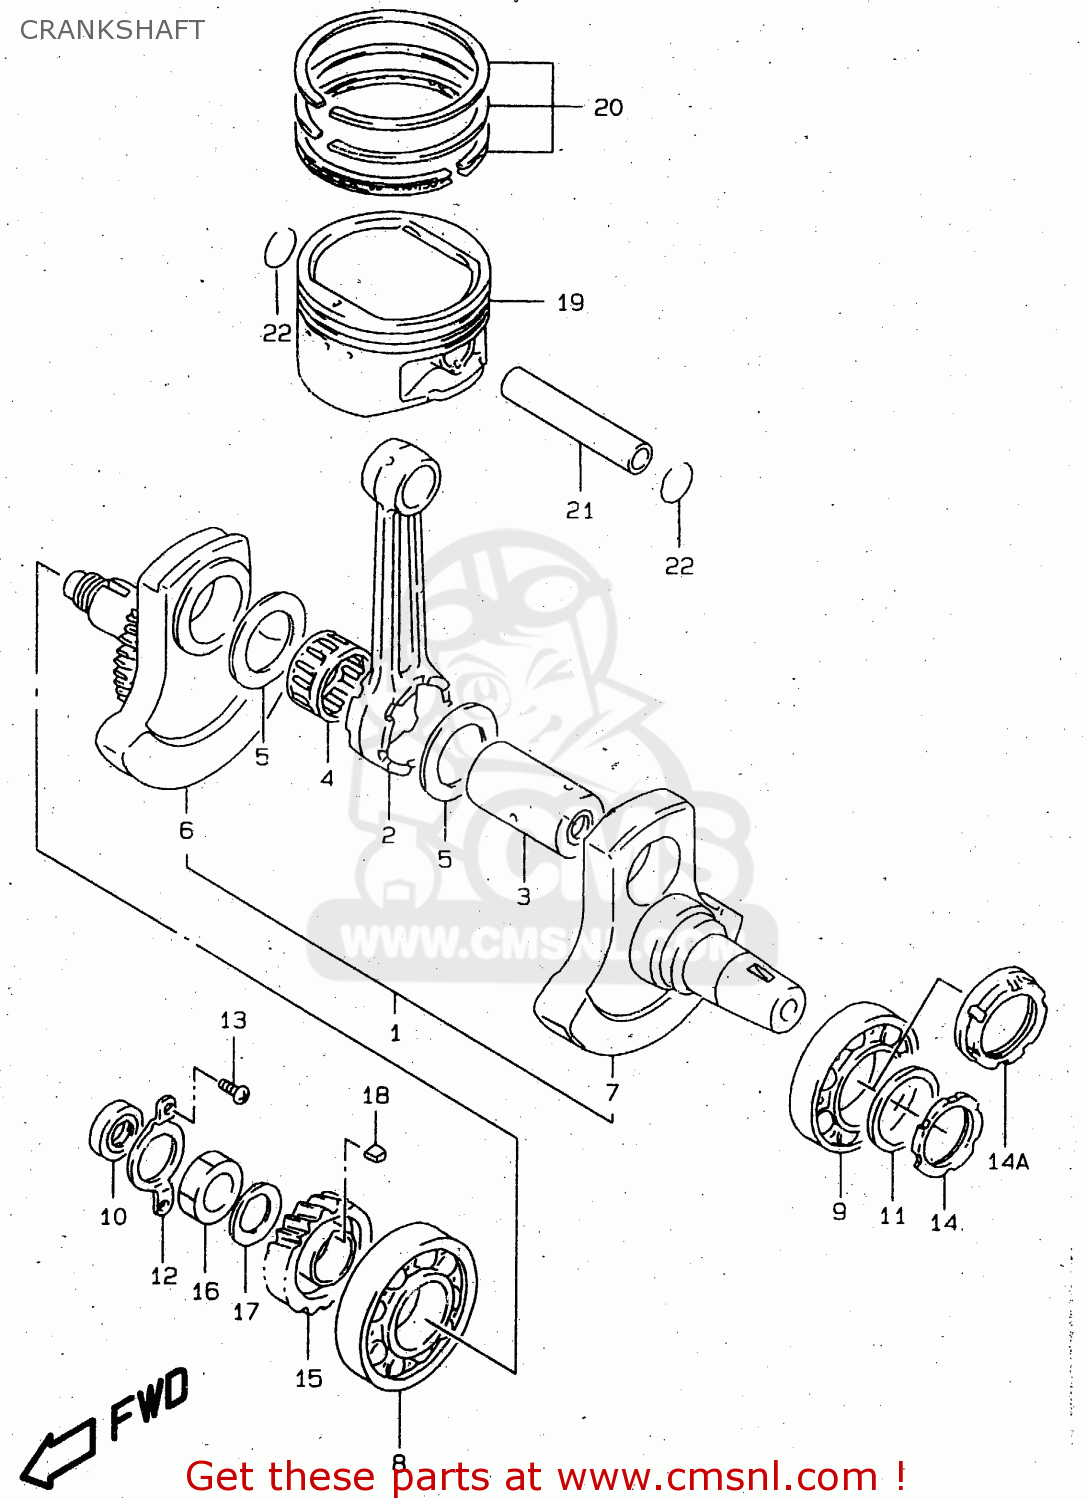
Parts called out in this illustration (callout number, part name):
1	CRANKSHAFT SET
2	CONNECTING ROD
3	PIN,CRANK
4	BEARING(37X47X25)
5	WASHER(37X55X1)
6	CRANKSHAFT SET,R
7	CRANKSHAFT,L
8	BEARING(40X80X18)
9	BEARING(45X85X19)
10	SEAL,OIL(16X30X6)
11	SPACER (40X54X5.5)
12	RETAINER,CRANKSHAFT BEARING,R
13	SCREW
14	NUT,BAL DRIVE SPRKT
14A	NUT,CRANKSHAFT BRG,L
15	GEAR,PRIMARY DRIVE(NT:28)
16	NUT (20MM)
17	WASHER
18	KEY
19	PISTON (100.00MM)
20	RING SET,PISTON
21	PIN,PISTON
22	CIRCLIP
